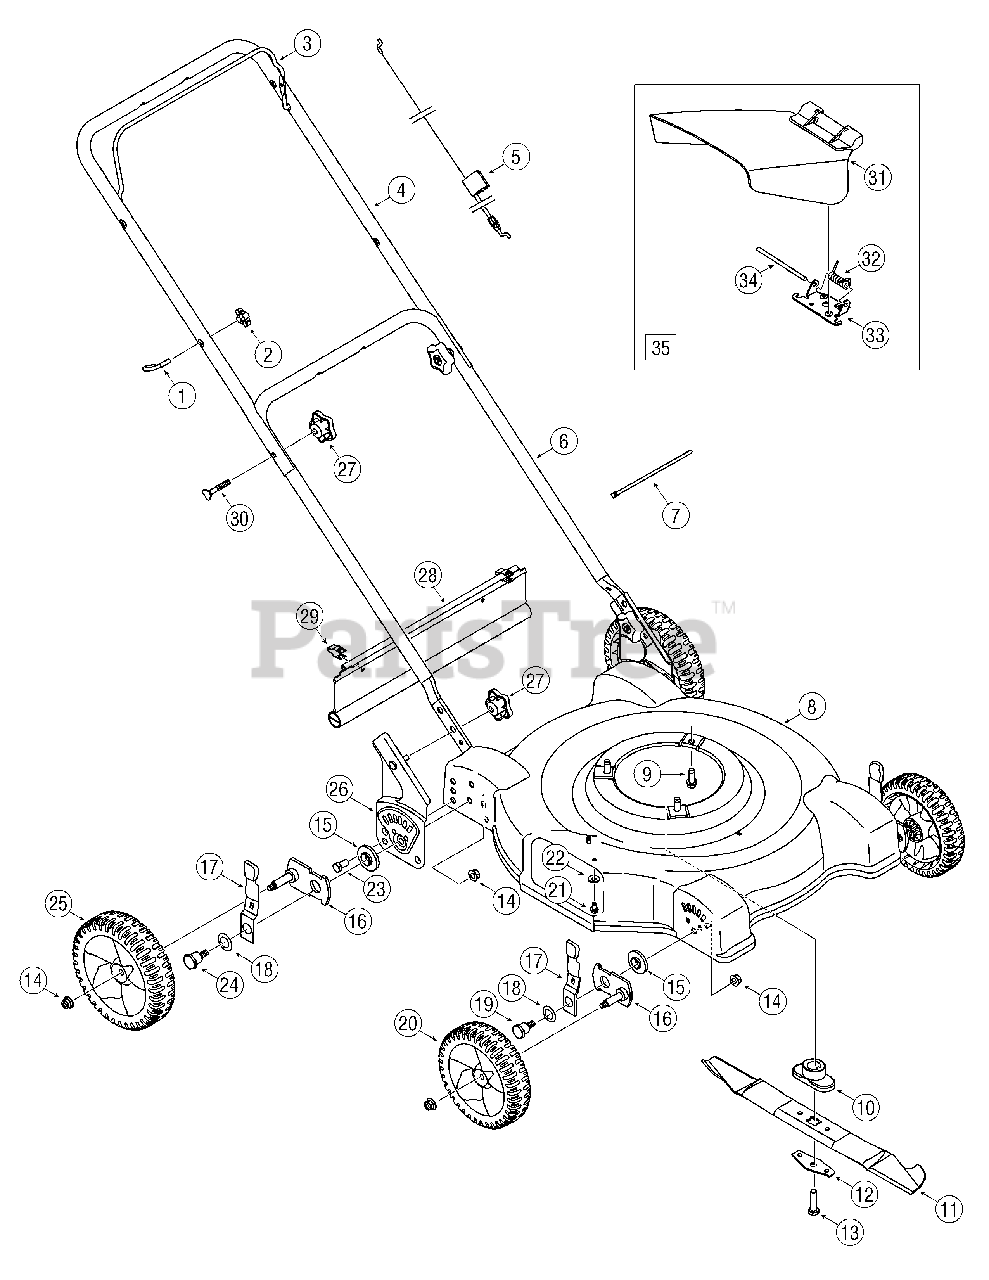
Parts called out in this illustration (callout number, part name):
1	Eye Bolt
2	Wing Nut
3	Blade Control Handle
5	Blade Control Cable - 37.25
5	Blade Control Cable - 48.25
5	Blade Control Cable - 40.00
7	Cable Tie
9	TT Screw 3/8-16 x 1.0
10	Blade Adapter 25MM X 1.19
10	Blade Adapter #6 X 1.19 W/STAR
11	Standard Blade 22-inch
12	Blade Bell Support
13	Screw 3/8-24 x 1.5
14	Lock Nut 3/8-16
15	Height Adjuster Bearing
16	Pivot Arm
17	Lever Assembly
18	Bell Washer .760 ID x 1.25
19	Shoulder Screw
20	Front Wheel 7 x 1.8
21	TT Screw 1/4-20 x .5
22	Bell Washer .265 ID x .75
23	Screw 3/8-16 x .75
24	Shoulder Screw
25	Rear Wheel 8 x 1.8
26	Handle Bracket Assembly RH
26	Handle Bracket Assembly LH
27	Star Knob
28	Trailshield
29	Hinge Clip
30	Carriage Bolt 5/16-18 x 2
31	Chute Deflector
32	Torsion Spring
33	Chute Hinge
34	Hinge Pin
35	Hinged Chute Deflector Assembly
